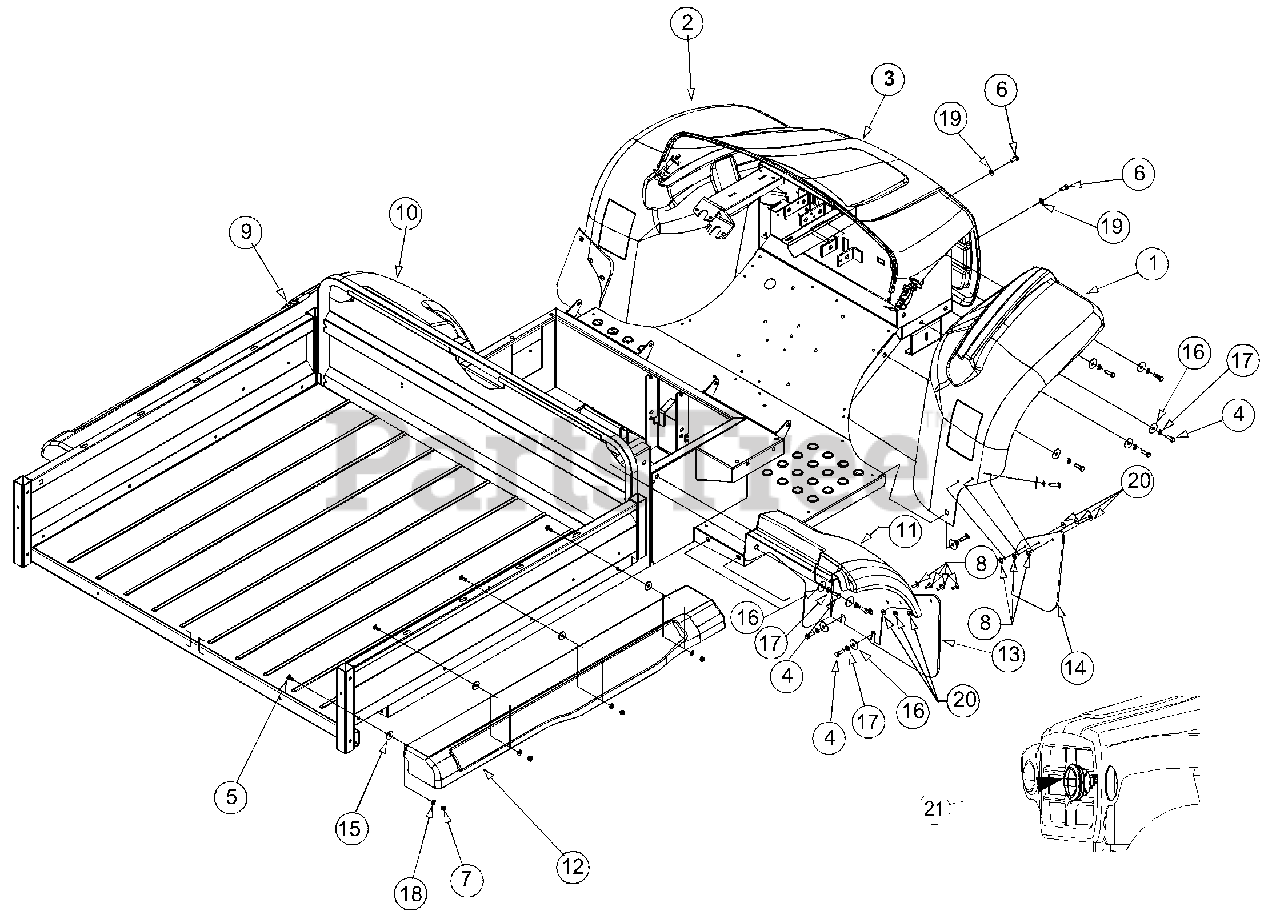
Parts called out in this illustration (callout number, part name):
1	Panel, Front Fender, RH
2	Panel, Front Fender, LH
3	Panel, Hood
4	Hex Screw, 5/16-18 x 1.0 Gr5
5	Hex Screw, 1/4-20 x .75
6	Hex Screw, 1/4-20
7	Hex Lock Nut, Nylon, 1/4-20
8	Pop Rivet
9	Panel, Bed Skirt, LH
10	Panel, Rear Fender, LH
11	Panel, Rear Fenders, RH
12	Panel Bed Skirt, RH
13	Mud Flap, Rear
15	Washer, Rubber, .310 x 1.0 x .125
16	Flat Washer, .350 x 1.25 x .06
17	Lock Washer, 5/16
18	Flat Washer, .271 x .630 x .065
19	Flat Washer, .344 x .688 x .0652
20	Flat Washer, .194 x .62 OD x .063
21	Headlight Assembly
